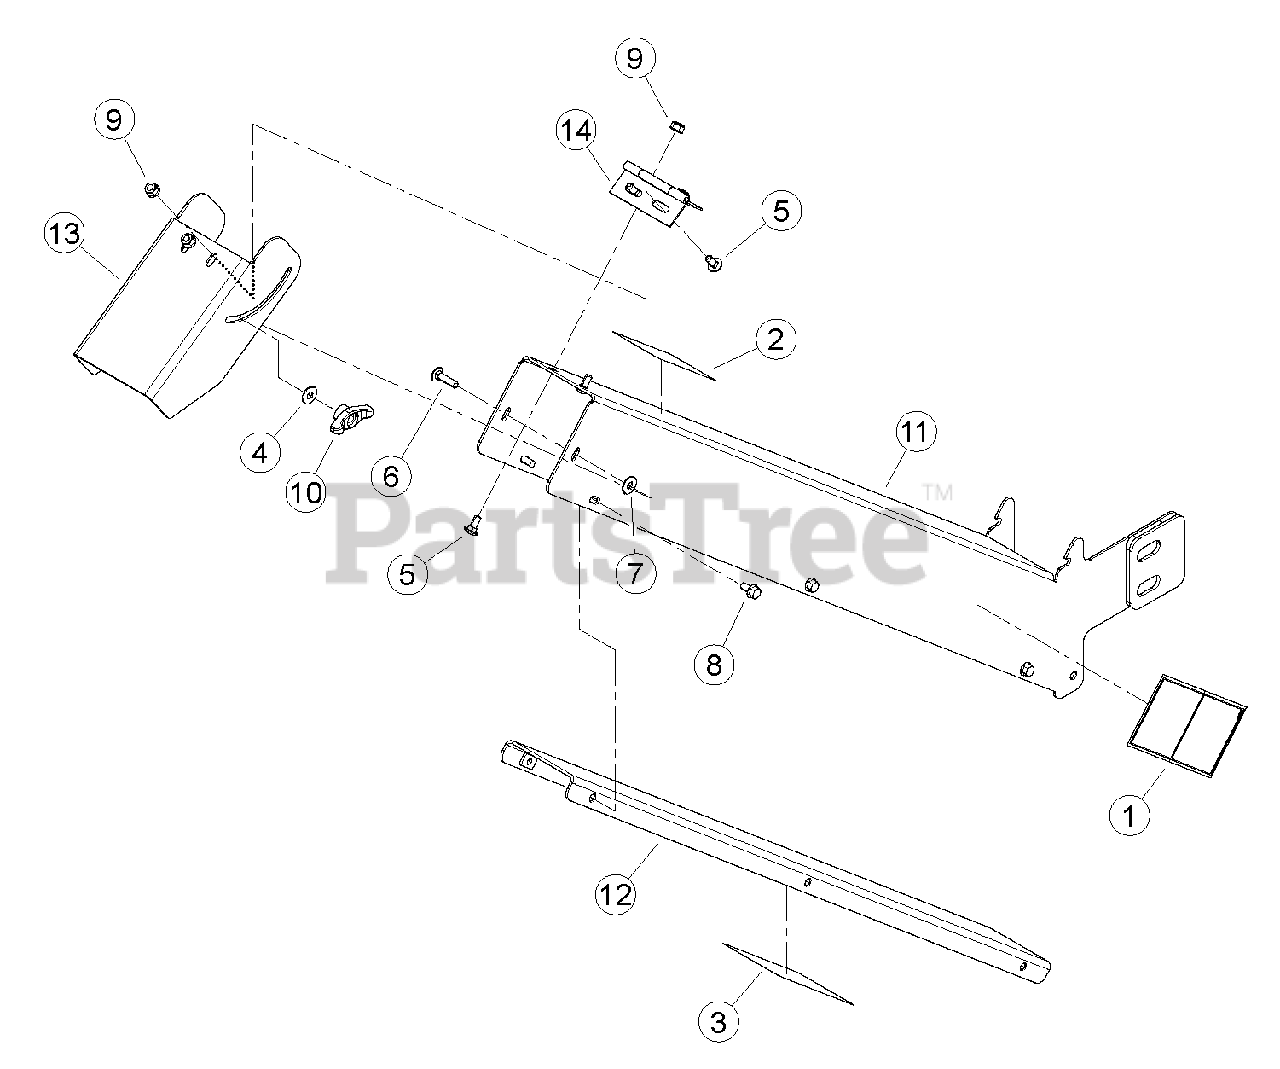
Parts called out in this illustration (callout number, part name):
1	DECAL, KNIFE ACCESS ISO
2	DECAL, DISCHARGE ISO
3	DECAL, BLADE DANGER ISO
4	WASHER, 5/16 FLAT
5	BOLT, 5/16X3/4 GR5 NC ZP CRG
6	BOLT, CARR 5/16 X 1-1/4 GR5 CMS F1 5ANS
7	WASHER, 5/16"ID 7/8"OD NYLON FLAT
8	BOLT, 5/16 X 5/8 FLANGE NC
9	NUT, 5/16-18 NYLOCK FLANGE
10	KNOB, 5/16-18 UNC TEE W/ LOCKING INSERT
11	WELDMENT, CHIPPER DISCHARGE
12	WELDMENT, TOP DISCHARGE CHUTE
13	CAP, DISCHARGE
14	HINGE, DISCHARGE CAP
